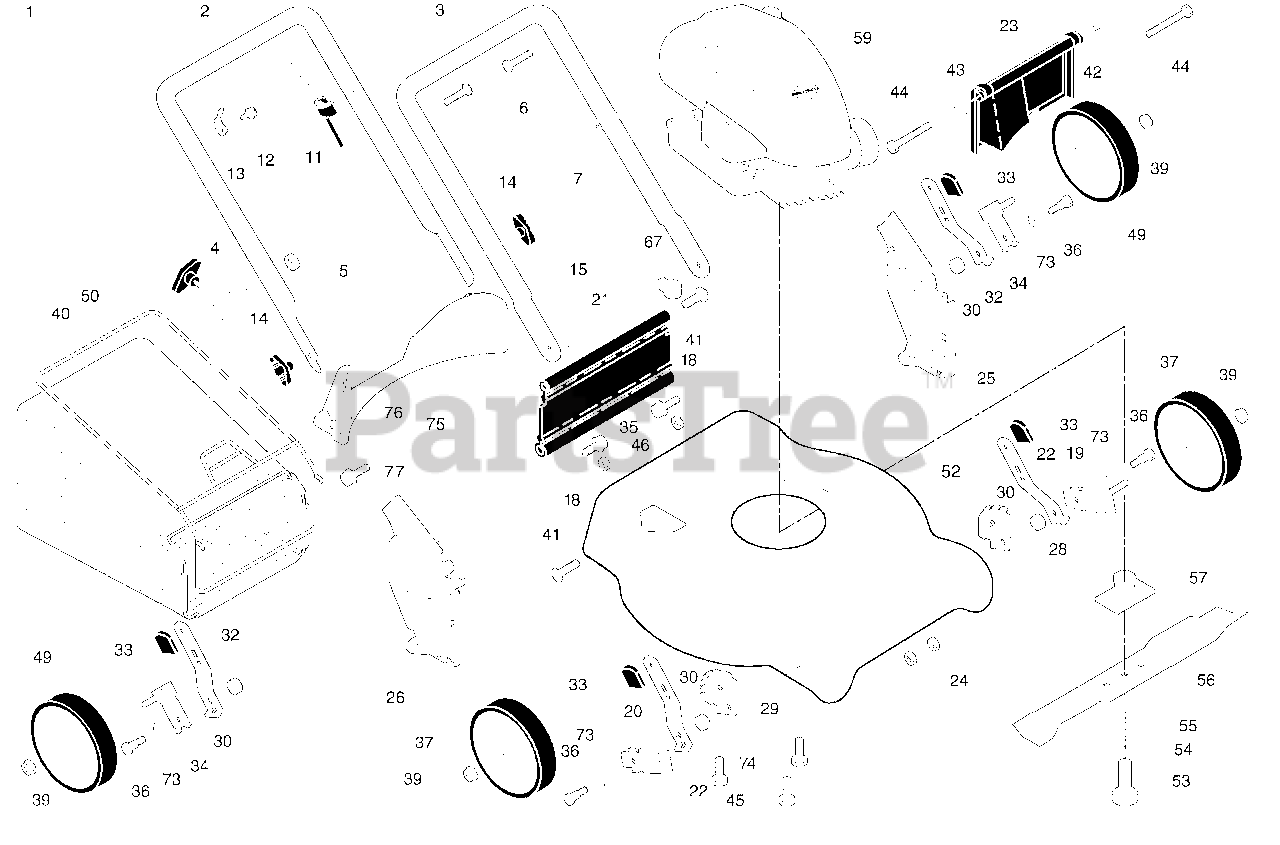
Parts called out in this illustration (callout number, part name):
1	Control Bar
2	Upper Handle
3	Lower Handle
4	Rope Guide
6	Handle Bolt
7	Wire Tie
11	Engine Zone Control Cable
12	Hex Washer Head Screw
13	Up-Stop Bracket
14	Handle Knob
15	Hairpin Cotter
18	Screw 1/4-20 x 3/8
19	Axle Arm Assembly, Front, LH
20	Axle Arm Assembly, Front, RH
21	Rear Skirt
22	Selector Spring, Front
23	Rear Door Assembly
24	Locknut, Hex
25	Handle Bracket Assembly, LH
26	Handle Bracket Assembly, RH
28	Wheel Adjusting Bracket, Front, LH
29	Wheel Adjusting Bracket, Front, RH
30	Spacer
32	Selector Spring, Rear
33	Selector Knob
34	Axle Arm Assembly, Rear
35	Locknut 5/16-18
36	Shoulder Bolt 5/16-18
37	Wheel & Tire Assembly, Front
39	Locknut, Hex, Flanged
40	Frame, Grass Bag
41	Hinge Screw
42	Spring, Rear Door, LH
43	Spring, Rear Door, RH
44	Bolt, Rear Skirt
45	Hex Head Thread Rolling Screw 3/8-16 x 1
46	Danger Decal
49	Wheel & Tire Assembly, Rear
50	Grass Bag
52	Housing Assembly
53	Hex Head Screw 3/8-24 x 1-3/8 Grade 8
54	Helical Lockwasher
55	Hardened Washer
56	21" Blade
57	Blade Adapter
67	Clip, Cable
73	Washer, Flat
74	Washer, Special, Engine
75	Kit, Rear Baffle
76	Baffle, Rear
77	Screw, Rear Baffle
77	Operator's Manual, English
77	Operator's Manual, Spanish
77	Repair Parts Manual
